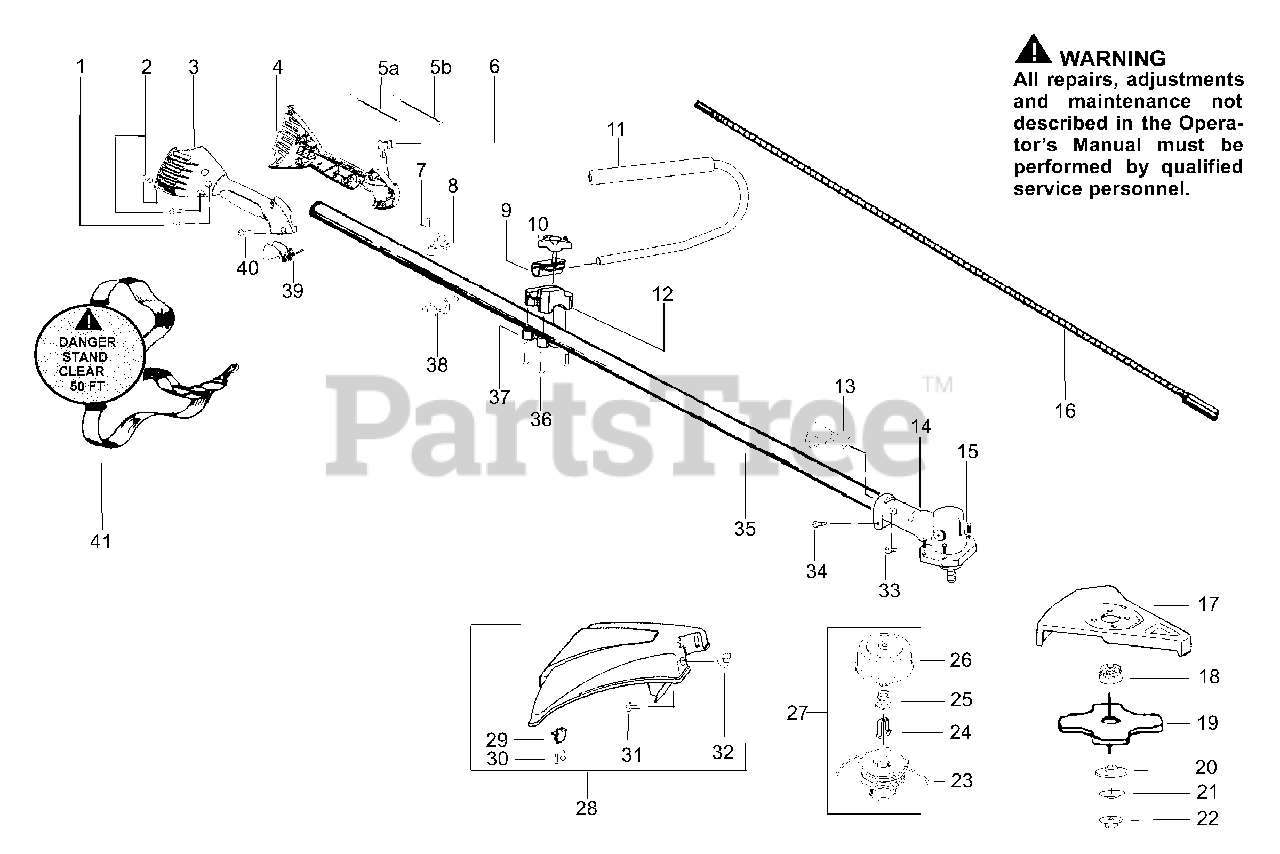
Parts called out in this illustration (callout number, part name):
1	Screw-alignment
3	Throttle hsg-right
4	Kit-Left throttle hsg
5A	Assy-Wire Assy-Front Wire
5B	Assy-Wire Assy-Front Wire
6	Kit-Switch
8	Clamp-Harness
9	Clamp-Handlebar
10	Knob
11	Assy.-Handlebar
12	Base-Clamp
13	Bracket-Shield
14	Kit-Gearbox
16	Shaft-Flex Drive
17	Kit-Metal Shield
18	Dust cup
19	Accy.-Weed Blade
21	Washer-Belleville
22	Nut-Flange
23	Accy-Wound Spool
24	Retainer-Spool
25	Spring-Return
26	Assy-Hub/Arbor
27	Assy-Cutting Head
28	Kit-Shield Assy.
29	Limiter-Line
30	Screw
32	Wingnut
35	Assy.-Driveshaft
37	Clamp-Tube
38	Clamp-Haress
39	Lever-Throttle
41	Shoulder Strap
